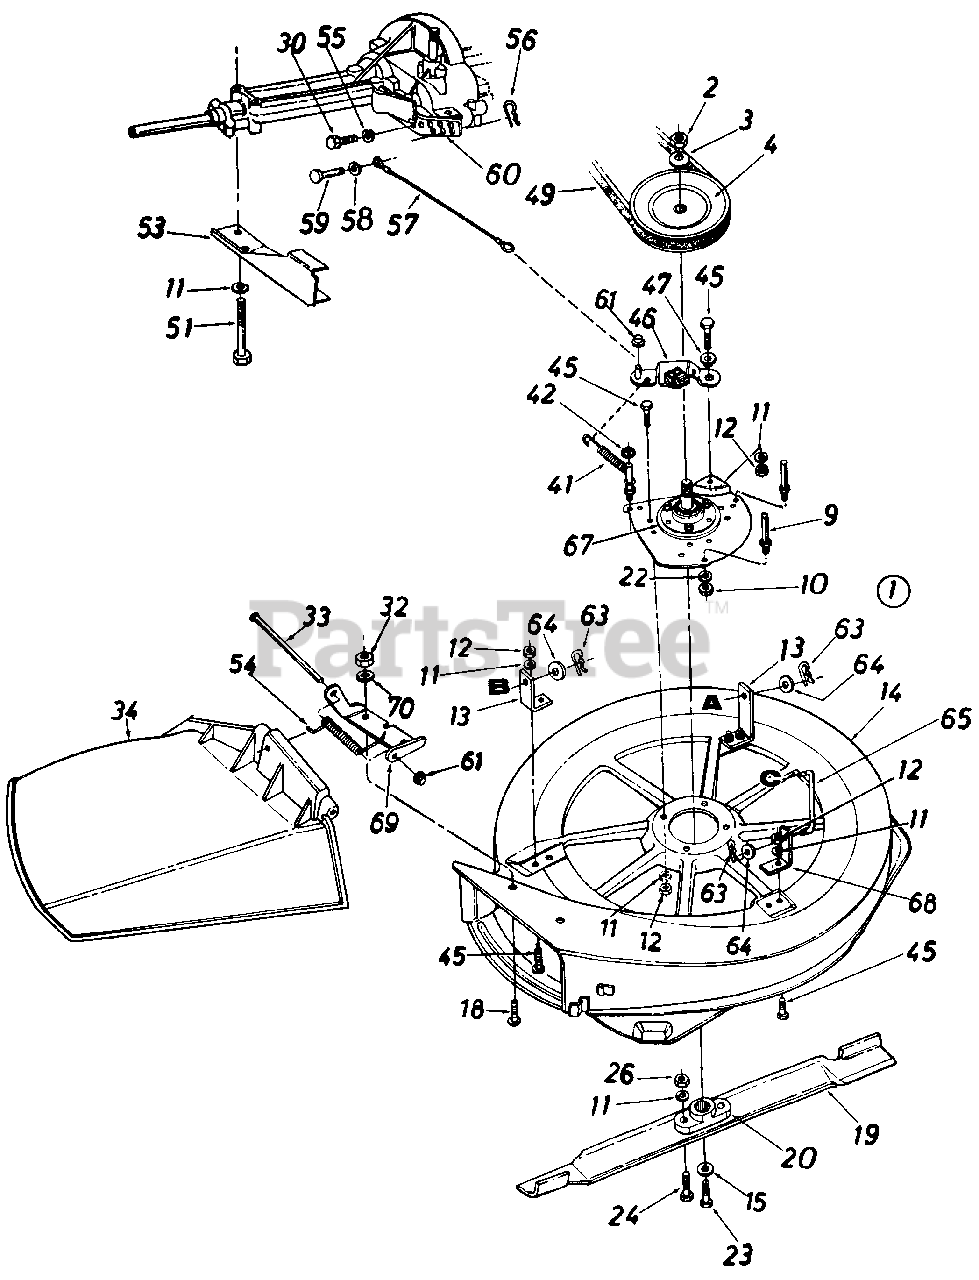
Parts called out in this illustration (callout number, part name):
1	30" S.D. Deck Ass'y. Comp.
2	Hex Jam Nut 5/8-18 Thd.
3	Bell-Wash. .630" I.D. x 1.25n
4	5/8 V-Pulley .75" I.D. x 7"
9	Stud 3/8-16 x 2 75" Lg.
10	Hex Jam Nut 3/8-16 Thd.
11	L-Wash. 5/16" l.D.
12	Hex Nut 5/16-18 Thd.
18	Truss Mach. Scr. 1/4-20 x .75" Lg.
19	30n High Lift Blade
20	Blade Adapter
22	L-Wash. 3/8" l.D.
23	Hex Bolt 3/8-24 x 1.0
24	Hex Bolt 5/16-24 x 1.0" Lg.
26	Hex Nut 5/16-24 Thd.
30	Hex Bolt 1/4-20 x 50n Lg.
32	Hex Nut 1/4-20 Thd.
33	Hinge Pin
34	Chute Ass'y. Comp.
41	Extension Spring .5" O.D. x 3.2" Lg.
42	Push Speed Nut
45	Hex Bolt 5/16-18 x .75
46	Blade Brake Brkt. Ass'y.
47	Shoulder Spacer .500n Dia.
49	"V"-Belt
51	Hex Bolt 5/16-18 x 2.75n
55	L-Wash. 1/4" I.D.
56	Int. Cot. Pin 5/16" Dia.
57	Brake Cable 9 75" Lg.
58	Fl-Wash. .281" l.D. x .50"
59	Clevis Pin 1/4" Dia.
60	Lower Inside Belt Guard
61	Cap Speed Nut 1/4" Rod
63	Int. Cotter Pin 1/2" Dia.
64	Fl-Wash. .531" I.D. x .930"
65	Deck Link 3.9" Lg.
67	Blade Spindle Ass'y. Comp.
68	Weld Bracket
69	Hinge Mtg. Brkt.
70	Bell-Wash. 1/4" I.D.
